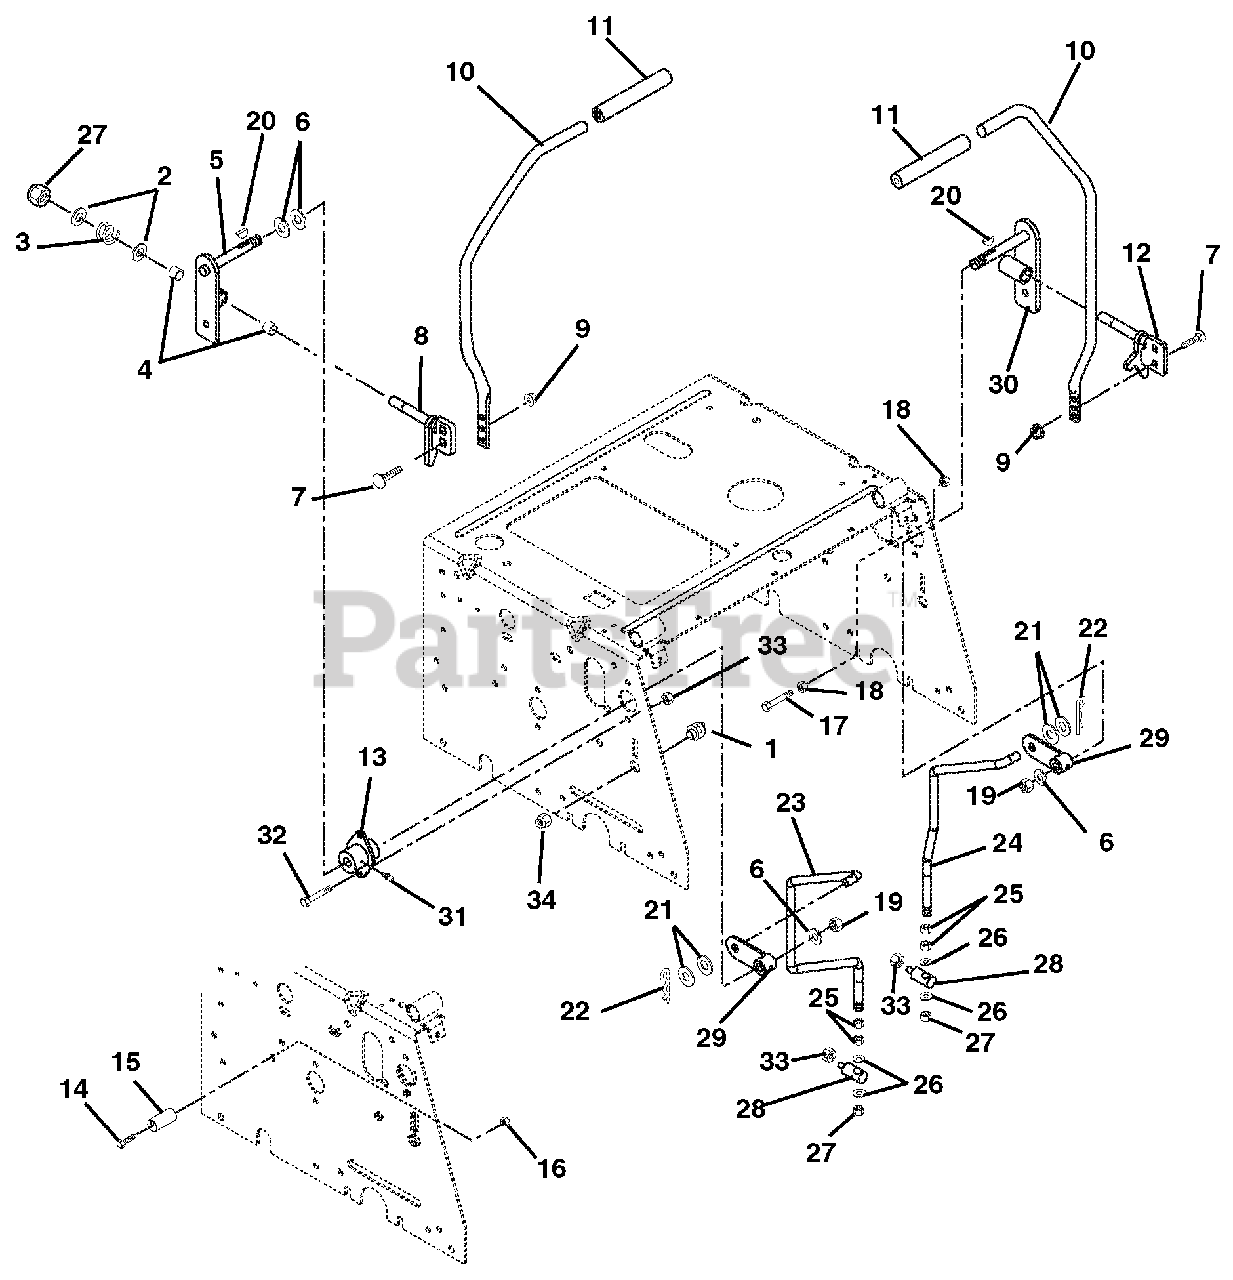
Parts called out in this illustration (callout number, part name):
1	Switch-Neutral
2	Washer-Plastic .12 x .53 x 1.12
3	Spring-Compression
4	Bushing-Nylon .5 x .625 x .5
5	Control Weldment Right Hand
6	Washer-Flat, Steel .563 x 1.375 x .109
7	Bolt-Round Head Square Neck .31-18 x .88 Grade 5
8	Weldment-Lever Right Hand
9	Nut-Locking-Top-Flange .31-18
10	Handlebar-Large Frame
11	Grip-Handlebar
12	Weldment-Lever Left Hand
13	Bushing-Flanged
14	Bolt-Hex .31-18 x 3.00 Grade 5
15	Eccentric
16	Nut-Locking-Nylon .312-18
17	Bolt-Hex .38-16 x 2.25 Grade 5
18	Nut-Flange .375-16
19	Nut-Jam-Locking-Nylon .50-20 Grade 2
20	Key-Woodruff .13 x .75
21	Washer-Flat-Steel .531 x 1.25 x .10
22	Pin-Hair-Internal .08 x .18 x 1.18
23	Rod-Transaxle Right Hand
24	Rod-Transaxle Left Hand
25	Nut-Jam .50-13
26	Washer-Flat Steel .505 x .88 x .072
27	Nut-Locking Nylock Thin .50-13
28	Rod-Pivot
29	Weldment-Pump
30	Control Weldment Left Hand
31	Fitting-Lube .25-28 x .256
32	Bolt-Serrated Hex Flange Washer Head .31-18 x .75
33	Nut-Locking-Center .312-18
34	Nut-Stamped .56-18
